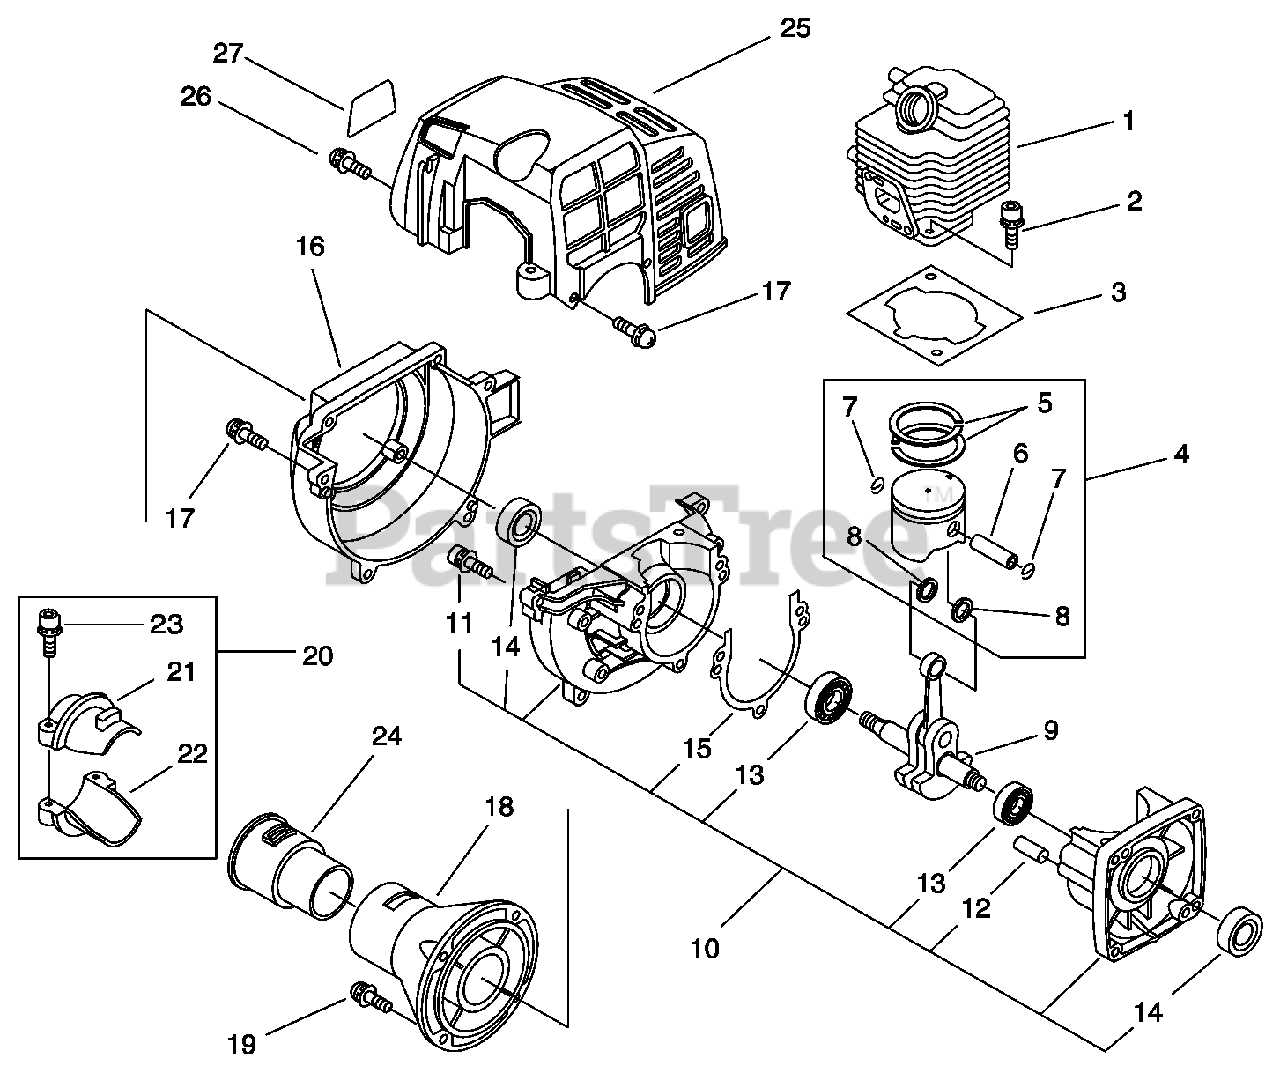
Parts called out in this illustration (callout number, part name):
1	CYLINDER
2	SCREW - 5X22
3	GASKET, CYLINDER
4	PISTON KIT
5	RING, PISTON
6	PIN, PISTON
7	RING, RETAINING
8	WASHER - 8
9	CRANKSHAFT ASSY
10	CRANKCASE KIT
11	SCREW - 5X28
12	PIN - LOCATING
13	BEARING, BALL - 6201
14	SEAL, OIL
15	GASKET, CRANKCASE
16	CASE, FAN - ORANGE
17	SCREW - 4X16
18	CASE, CLUTCH
19	SCREW - 5X16
20	HOLDER KIT
23	SCREW - 5X25
25	COVER, ENGINE
26	SCREW - 4X12
27	LABEL - ECHO
